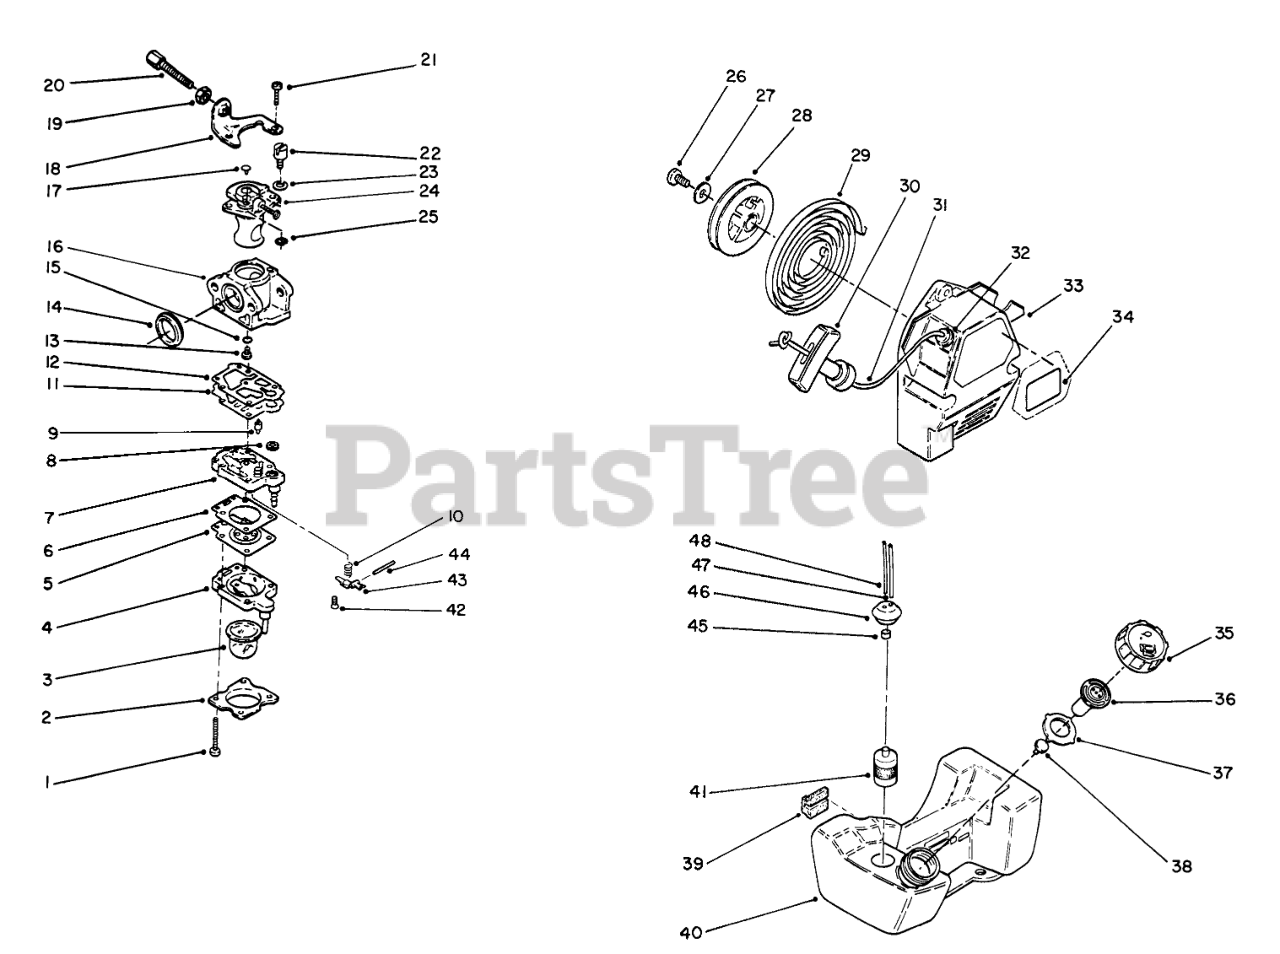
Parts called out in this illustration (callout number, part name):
1	Screw
2	Cover-Primer
3	PRIMER PUMP
4	Body-Primer
5	DIAPHRAGM
6	DIAPHRAGM GASKET
7	Body Ass-y-Fuel Pump (Incl. Ref. #8)
8	SCREEN
9	NEEDLE VALVE
10	Spring
11	DIAPHRAGM
12	DIAPHRAM GASKET
13	MAIN JET
13	Jet-High Altitude #41
14	RUBBER CARB GASKET
15	MAIN JET O-RING
16	Body-Carburetor (Ref.)
18	BRACKET
19	LOCKNUT
20	ADJUSTING SCREW
21	SCREW
22	Holder-Wire
23	WASHER
24	THROTTLE VALVE
26	SCREW
27	Washer
29	SPRING
30	Knob-Starter
31	Rope-Recoil
32	GUIDE
33	RECOIL CASE
34	Decal-Toro
35	FUEL TANK CAP
36	BREATHER VALVE
37	PACKING
40	Tank Assembly-Fuel (Incl. Ref. #35-38 & 48)
41	FUEL FILTER
42	Screw
43	Lever
45	COLLAR
46	FUEL TANK GROMMET
47	FUEL TUBE
48	RETURN FUEL HOSE
